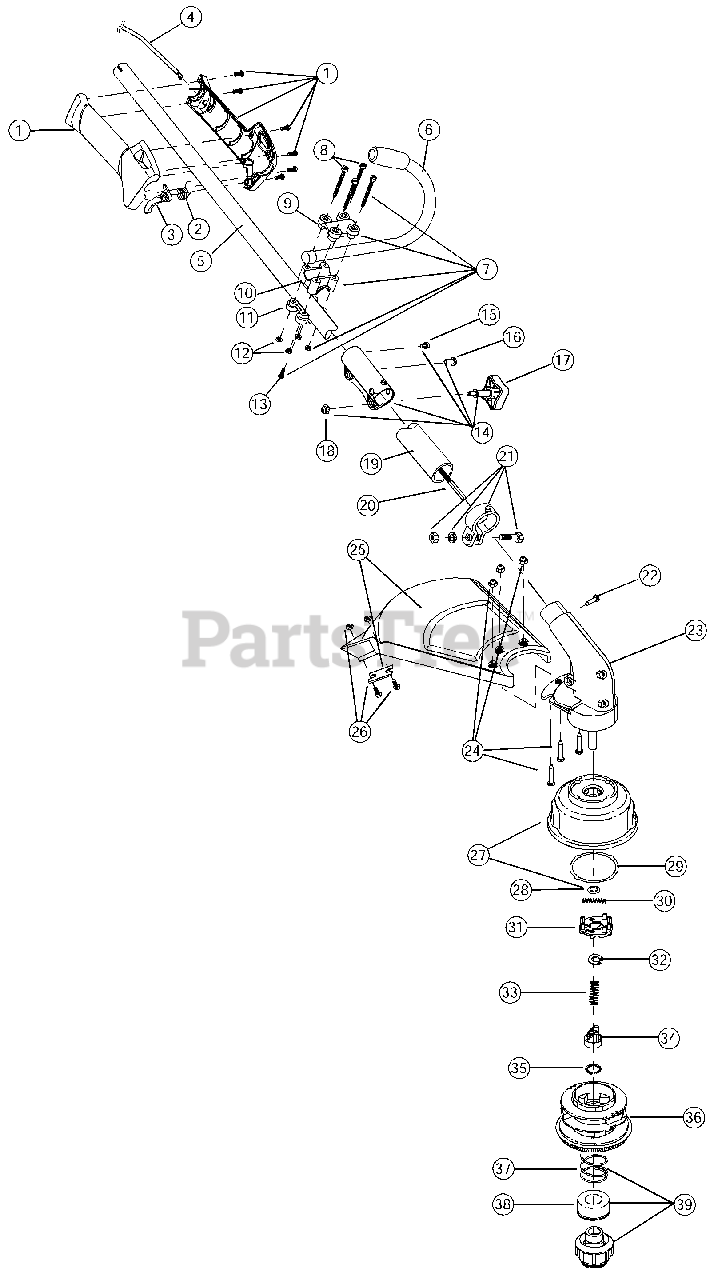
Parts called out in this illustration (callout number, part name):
1	Throttle Housing & Trigger Assembly
2	Throttle Trigger Spring
3	Throttle Trigger
4	Throttle Cable Assembly
5	Upper Drive Shaft Housing Assembly
6	J-Handle Assembly
7	Handle Bracket Assembly
9	Upper Handle Clamp
10	Middle Handle Clamp
11	Lower Handle Clamp
13	Anti-Rotation Screw
14	Split-Boom Coupler
17	Adjustment Knob
18	Knob Retaining Nut
19	Lower Drive Shaft Housing Assembly
20	Lower Flexible Drive Shaft
21	Lower Clamp Assembly
22	Anti-Rotation Screw
23	Gearbox Assembly
24	Shield Mounting Hardware
25	Shield and Blade Assembly
26	Blade Assembly
27	Outer Spool Assembly
28	Retainer
29	Thrust Washer
30	Small Spring
31	Slider
34	Plunger
36	Inner Reel
37	Large Spring
38	Foam Seal & Washer
39	Bumb Head Knob Assembly
